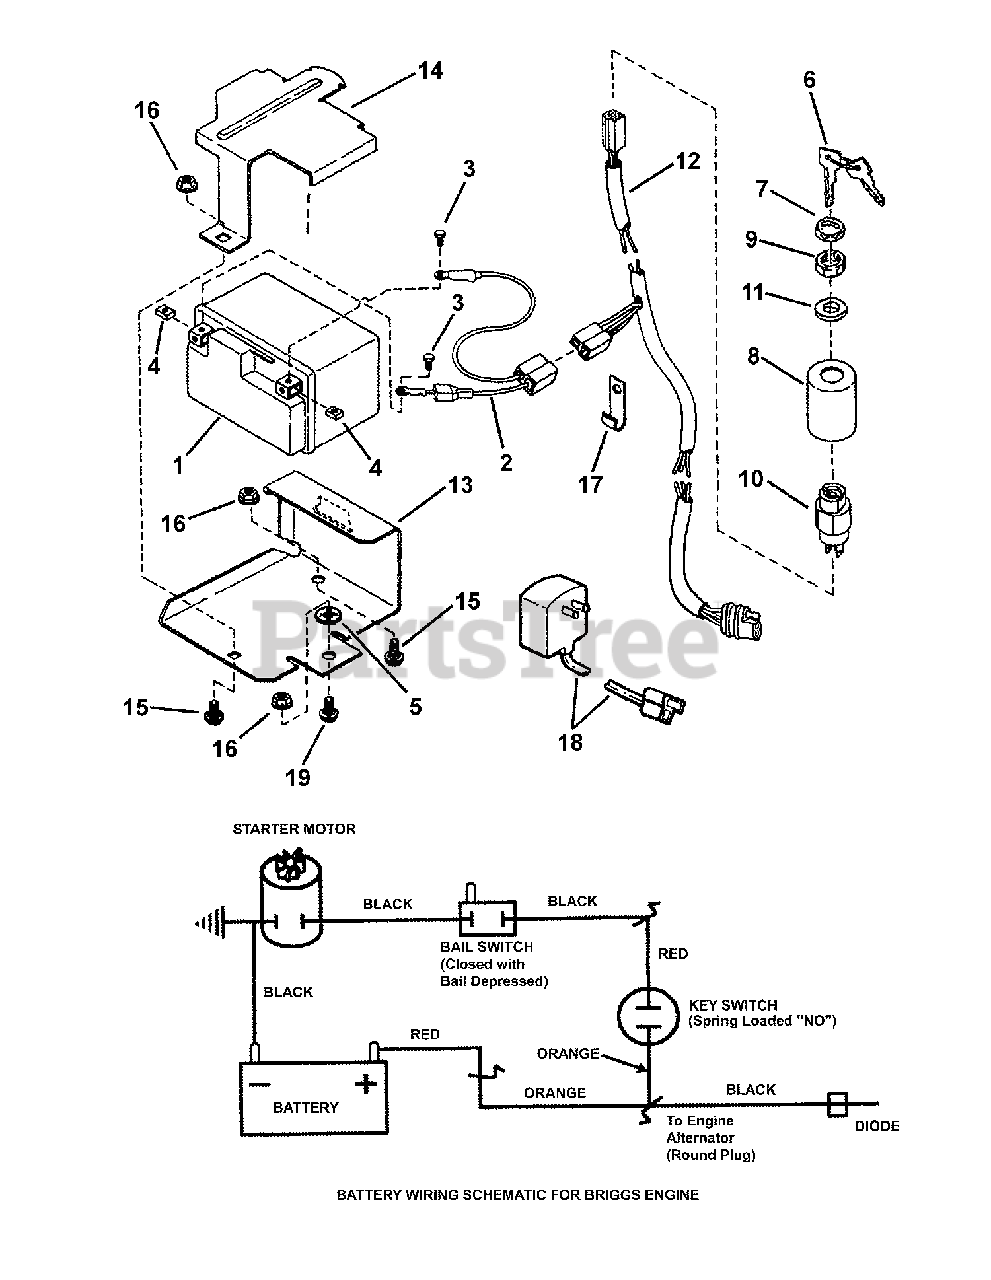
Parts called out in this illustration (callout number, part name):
1	KIT, BATTERY, 12 Volt, 35 CCA (includes items #1 and 2)
2	HARNESS, Battery
3	SCREW, #10-24 x 1/2" Pan Head Machine
4	NUT, #10-24 Square
5	RETAINER, 5/16" Bolt
6	KEY, (Set of Two)
7	BEZEL, (Seal & Face Nut)
8	COVER, Switch
9	NUT, 5/8-32 Hex Lock
10	SWITCH, Ignition (spring loaded ON/OFF 2 prong)
11	SPACER
12	WIRING HARNESS, B&S WBM
13	BRACKET, Battery
14	COVER, Battery
15	BOLT, 5/16-18 x 1/2" Short Neck Carriage GR 5
16	NUT, 5/16-18 Hex Flange Lock, GR 5 YZ
17	CLIP, Wiring
18	CHARGER, Battery (120 Volt; 60 Hertz)
19	BOLT, 5/16-18 x 5/8" Short Neck Carriage GR 5
